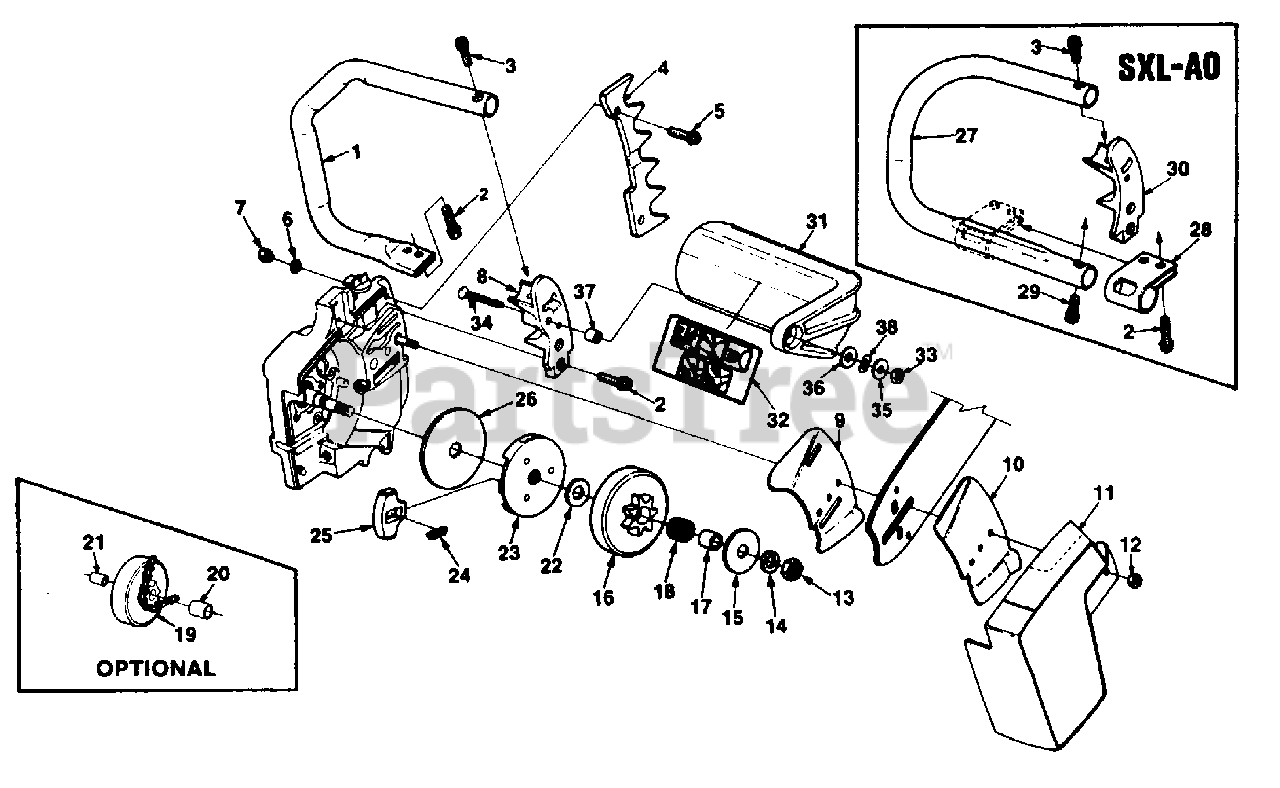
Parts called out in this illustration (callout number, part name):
2	SCREW- 12-24 x 3/4
3	SCREW- Socket hd. 1/4-20 x 1
4	BUMPER KIT- Spiked (Accessory)
5	SCREW- Hex 12-24 x 3/4
6	WASHER- Lock #12
7	NUT- Hex 12-24
8	KIT- Guide bar plate
9	PLATE- Guide bar (inner)
10	PLATE- Guide bar (outer)
11	COVER- Drivecase
12	NUT- Hex 3/8-16
13	NUT- Lock 3/8-24
14	WASHER- Lock 3/8
15	WASHER- Thrust (outer)
16	SPROCKET & DRUM 7 tooth (std.) 3/8,7 tooth
17	RACE- Inner
18	BEARING- Roller
19	SPROCKET & DRUM (opt.) 3/8" pitch, 8T
20	BEARING- Needle
21	RACE- Inner
22	WASHER- Thrust (inner)
23	PLATE- Clutch
24	SPRING- Clutch
25	SHOE- Clutch
26	COVER- Clutch
27	HANDLE BAR- Flush cut
28	CLAMP
29	SCREW- Soc. hd. 1/4-20
30	BRACKET- Handle bar
31	GUARD- Hand
32	DECAL
33	NUT- 12/24
34	SCREW- (12-24 x 1 1/4)
35	WASHER (5/16)
36	WASHER
38	WASHER- Spring wave
